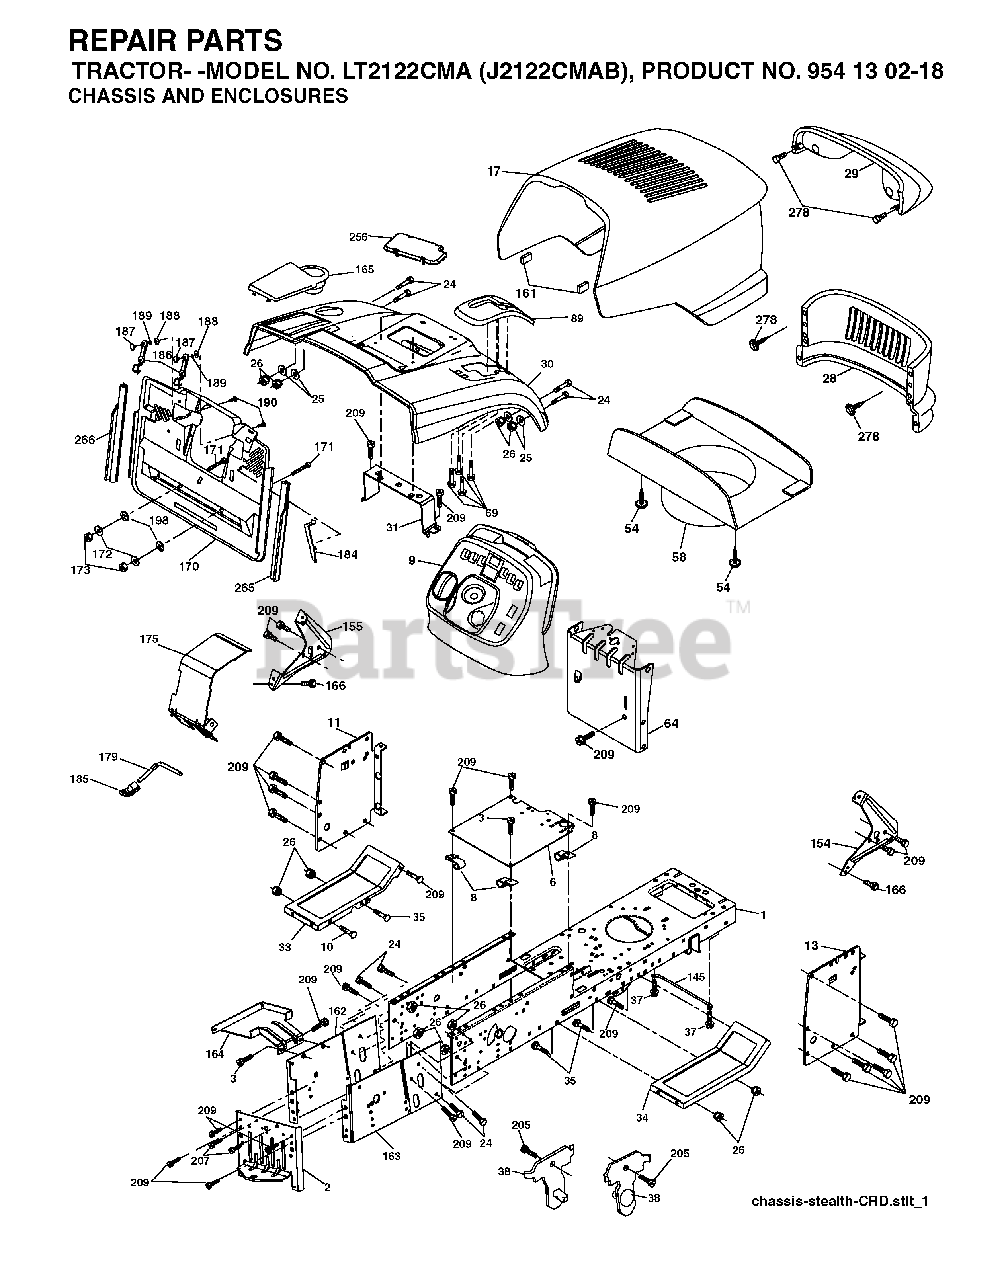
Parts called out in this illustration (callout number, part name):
1	CHASSIS
3	SCREW 3/8-16X3/4
8	CLIP,INSULATOR
10	BOLT D
13	PANEL DASH RH
25	WASHER
26	NUT
31	BRACKET SUPPORT FENDER
58	DUCT HOOD
69	SCREW.HI-LO.CONSOLE
145	ROD PIVOT CHASSIS/HOOD
161	EXTRUSION BUMPER
164	SUPPORT
166	SCREW
171	BOLT
172	WASHER
186	LATCH ASSY
187	WELDNUT
189	LOCKWASHER
207	SCREW, 5/16-18 X 1/2
209	SCREW, 3/8-16X3/4
278	SCREW
